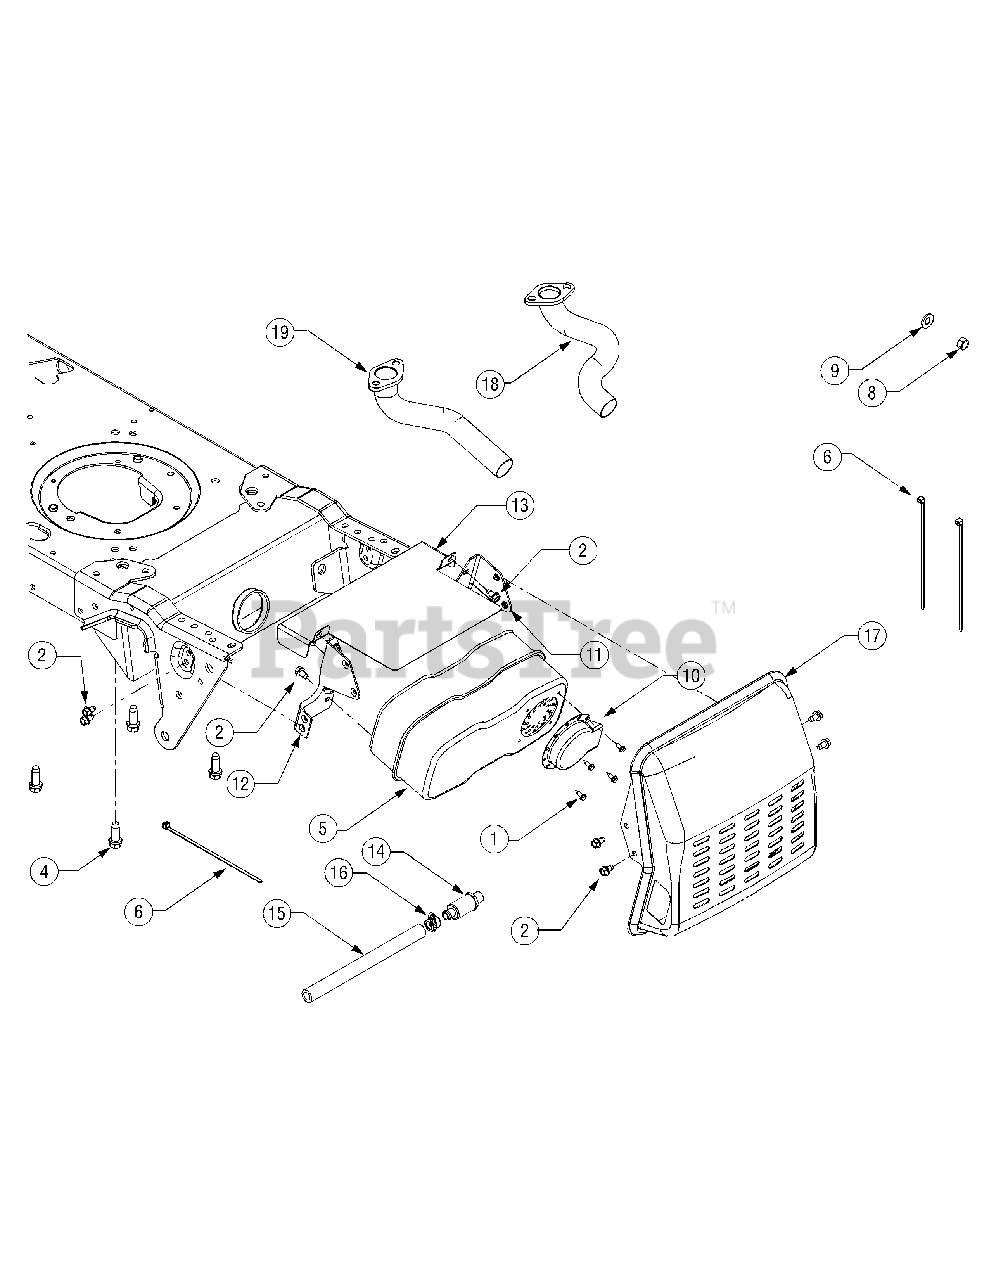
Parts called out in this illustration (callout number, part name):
1	Screw, #8-18, 0.500
2	Screw, Hex, 1/4-20, 0.500
3	Screw, Hex, 5/16-12 x .75
4	Screw, Hex, 3/8-16 x 1.25
5	Muffler, Dual Inlet
6	Cable, Tie, 3/16 x .05 x 7.4
7	Nut, Flange Lock, 5/16-18
8	Hex Flange Nut, 3/8-16
9	Lock Washer,.406 x.875 x.059
10	Deflector, Muffler
14	Drain, Oil
15	Extension Hose, Oil Drain
16	Cap, Oil Drain
18	Pipe, Exhaust, LH
19	Pipe, Exhaust, RH
